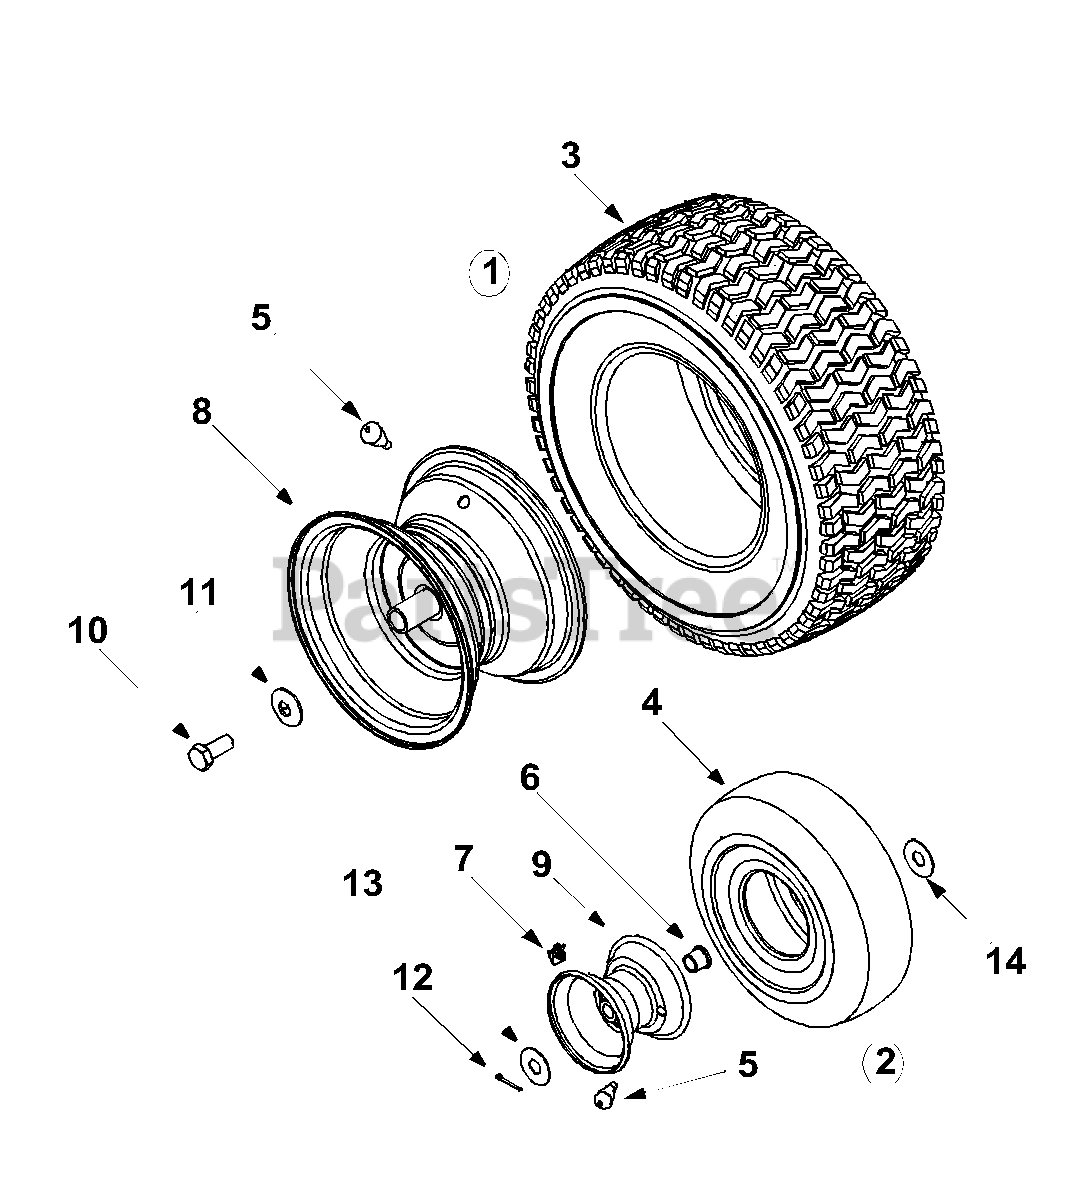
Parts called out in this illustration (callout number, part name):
5	Valve: Tubeless Air
6	Grease Fitting
7	Flange Bearing
11	Beleville Washer
